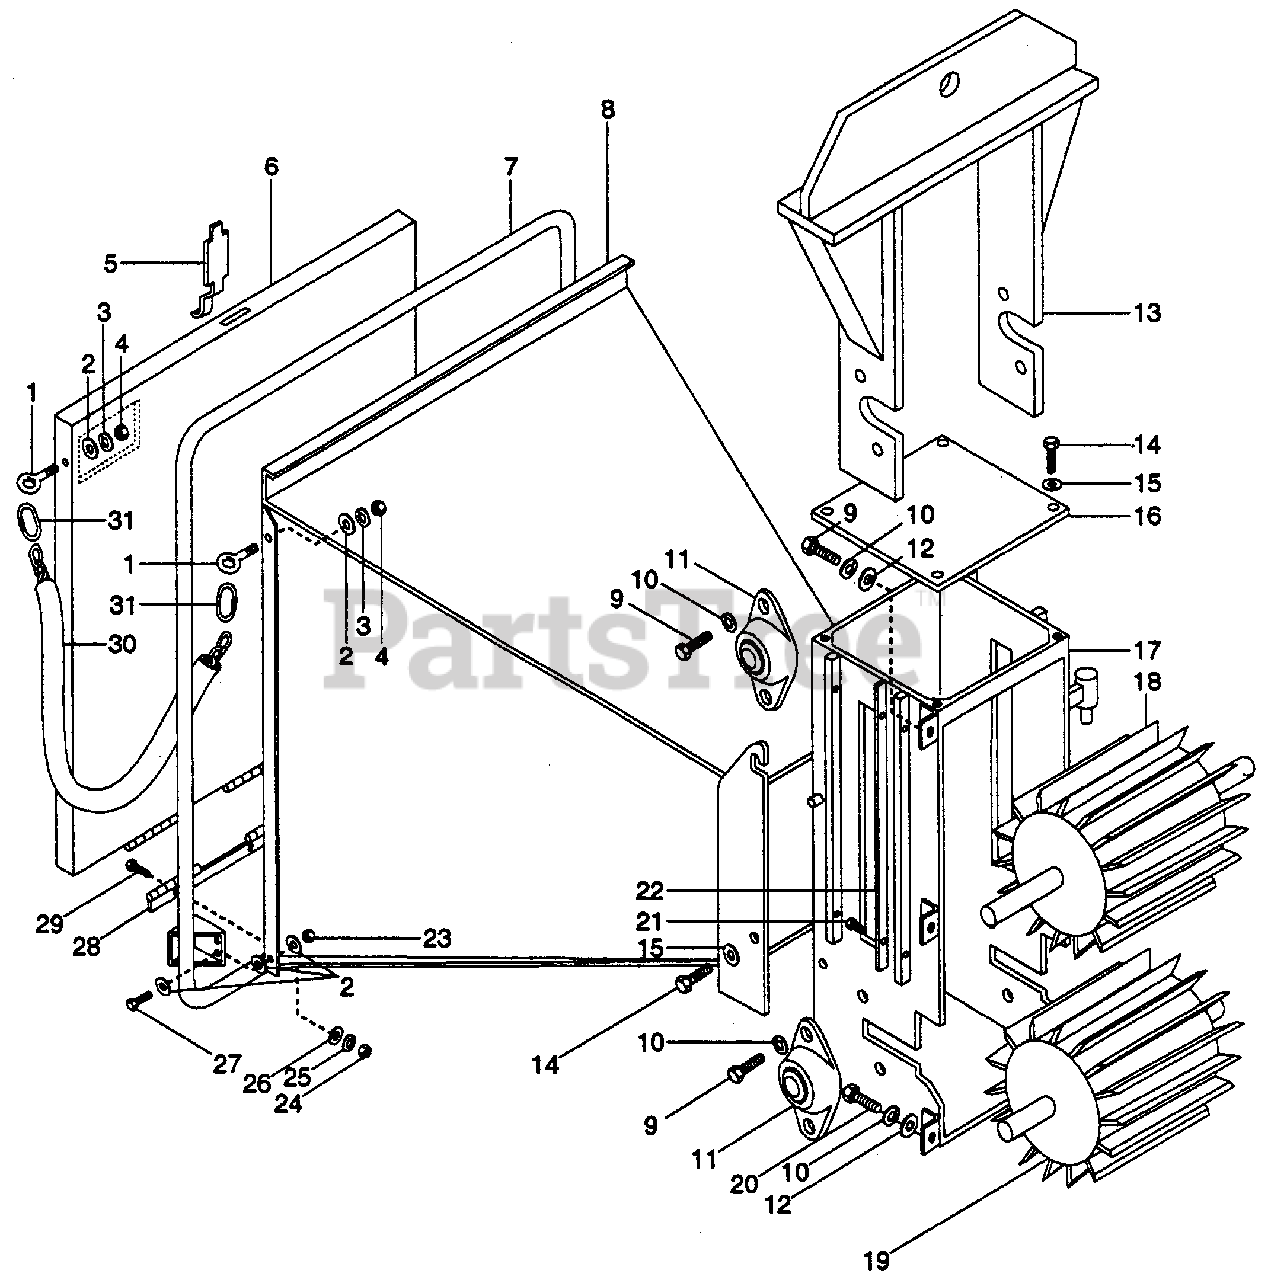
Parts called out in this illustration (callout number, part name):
1	Turned Eye Bolt
2	Wshr-Fl Stl .438 x 1.0 x .083 Pl
3	Wshr-Lock .375 x .094 Med Pl
4	Nut-Hex .375 x .094 Med Pl
6	Apron Weldment
7	Safety Loop Weldment
8	Hopper Weldment
9	Blt-Hex .50-13 x 1.25 Pl Gr 5
10	Wshr-Lock .500 x 1.51 Hvy Pl
11	Brg 2 Bolt-Flg
12	Wshr-Fl-Stl .531 x 1.062 x .095 Pl
13	Saddle Weldment
14	Blt-Hex .38-16 x .75 Pl Gr 5
15	Wshr-Fl-Stl .406 x .812 x .065 Pl
16	Cover
17	Feed Roller Box Weldment
18	Upper Feed Roller Weldment
19	Lower Feed Roller Weldment
20	Blt-Hex .50-13 x l.00 Pl Gr 8
21	Scr-Skh .25-20 x.50 FltCntSk
22	Front Rub Strip
23	Nut-Lk .375-16 Gr A Pl
24	Nut .250-20 Pl
25	Wshr-Lock .250 x .007 Hvy Pl
26	Wshr-Fl Stl .281 x .62 x .065 Pl
27	Blt-Hex .38-16 x 1.75 Pl Gr 5
28	Apron-Hinge-Cut
29	Blt-Hex .25-20 x .75 Pl Gr 5
